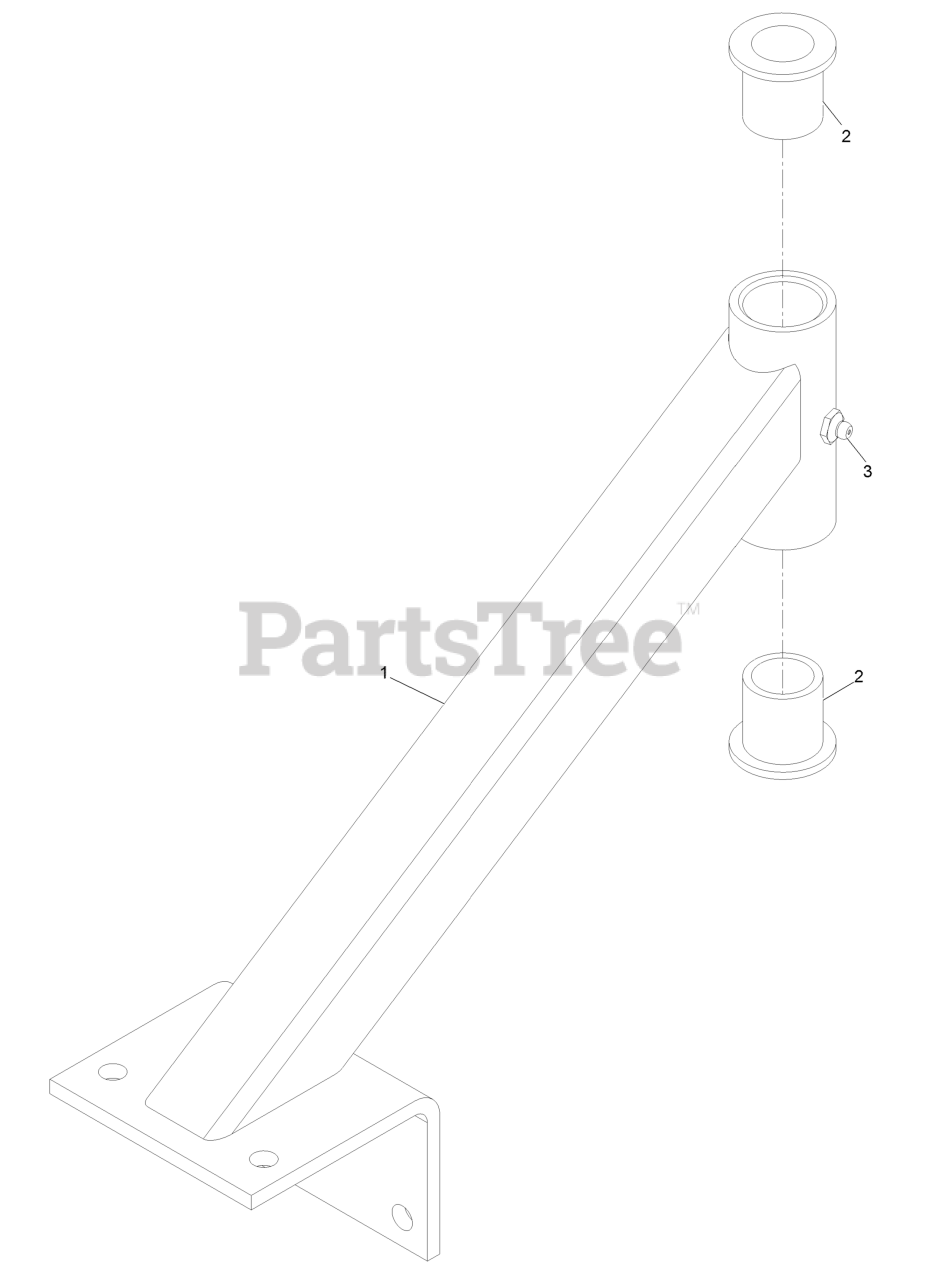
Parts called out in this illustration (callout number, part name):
1	Caster Whl Support Wldmnt, Weighted
2	Bearing-Flanged
3	Fitting-Grease
